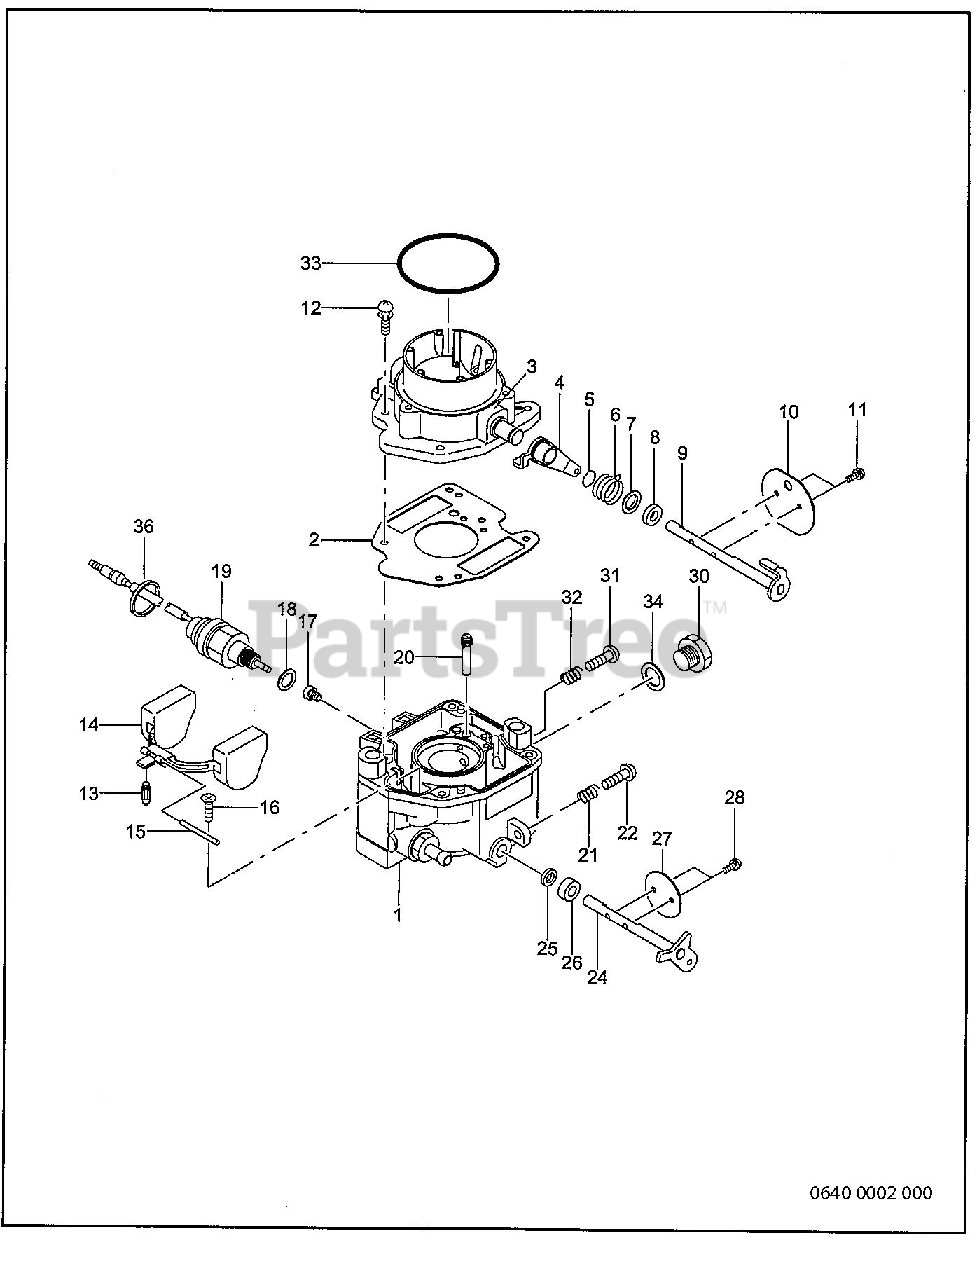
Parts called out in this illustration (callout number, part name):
1	CARBURETOR ASSY
2	GASKET, air horn
4	CHOKE LEVER ASSY
5	RING, choke lever
8	FILTER, choke shaft
9	SHAFT ASSY, choke
11	SCREW, valve set
12	SCREW, air horn set
16	SCREW, float pin set
17	MAIN JET (#132)
19	SOLENOID VALVE ASSY
20	JET, slow (#60)
21	SPRING, adjust screw
22	SCREW, throttle adjust
24	THROTTLE SHAFT ASSY
25	FILTER, throttle shaft
27	THROTTLE VALVE
28	VALVE SET SCREW
